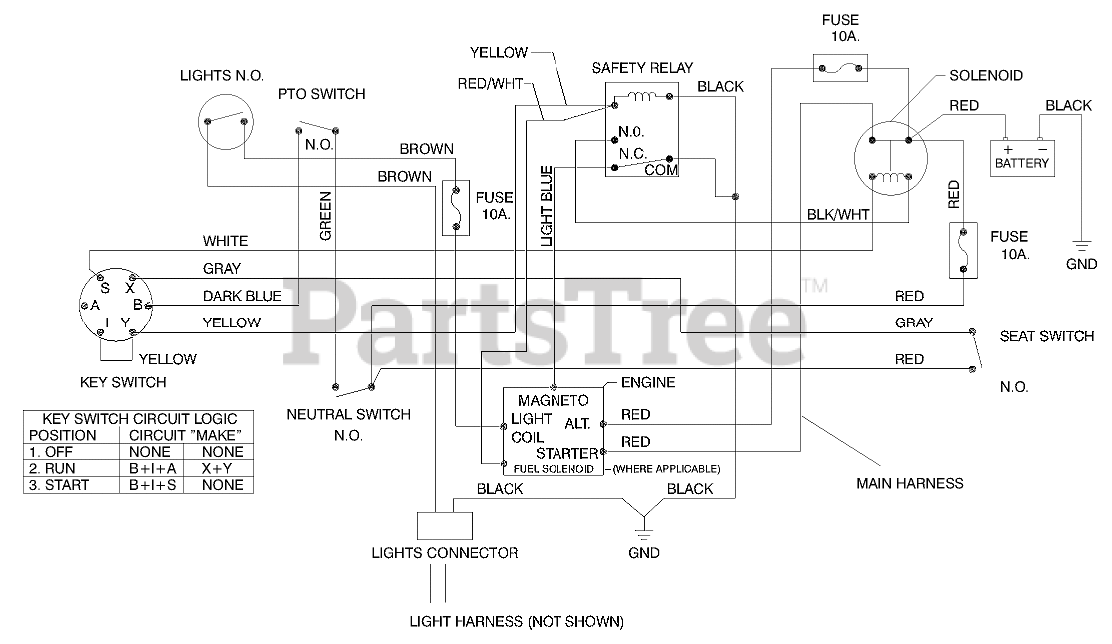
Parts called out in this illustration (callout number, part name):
1	NUT-LOCK, NI
2	SCREW-HH
3	GUIDE-BELT, LH
4	ANCHOR-GUIDE, BELT
5	GUIDE-BELT, RH
6	MUFFLER
7	SCREW-HH
8	WASHER-LOCK
9	Decal-Engine (Only On: 71201)
10	Engine-12 Hp B&s I/C (Only On: 71201)
10	Engine-12hp B&s STD (Only On: 71188)
